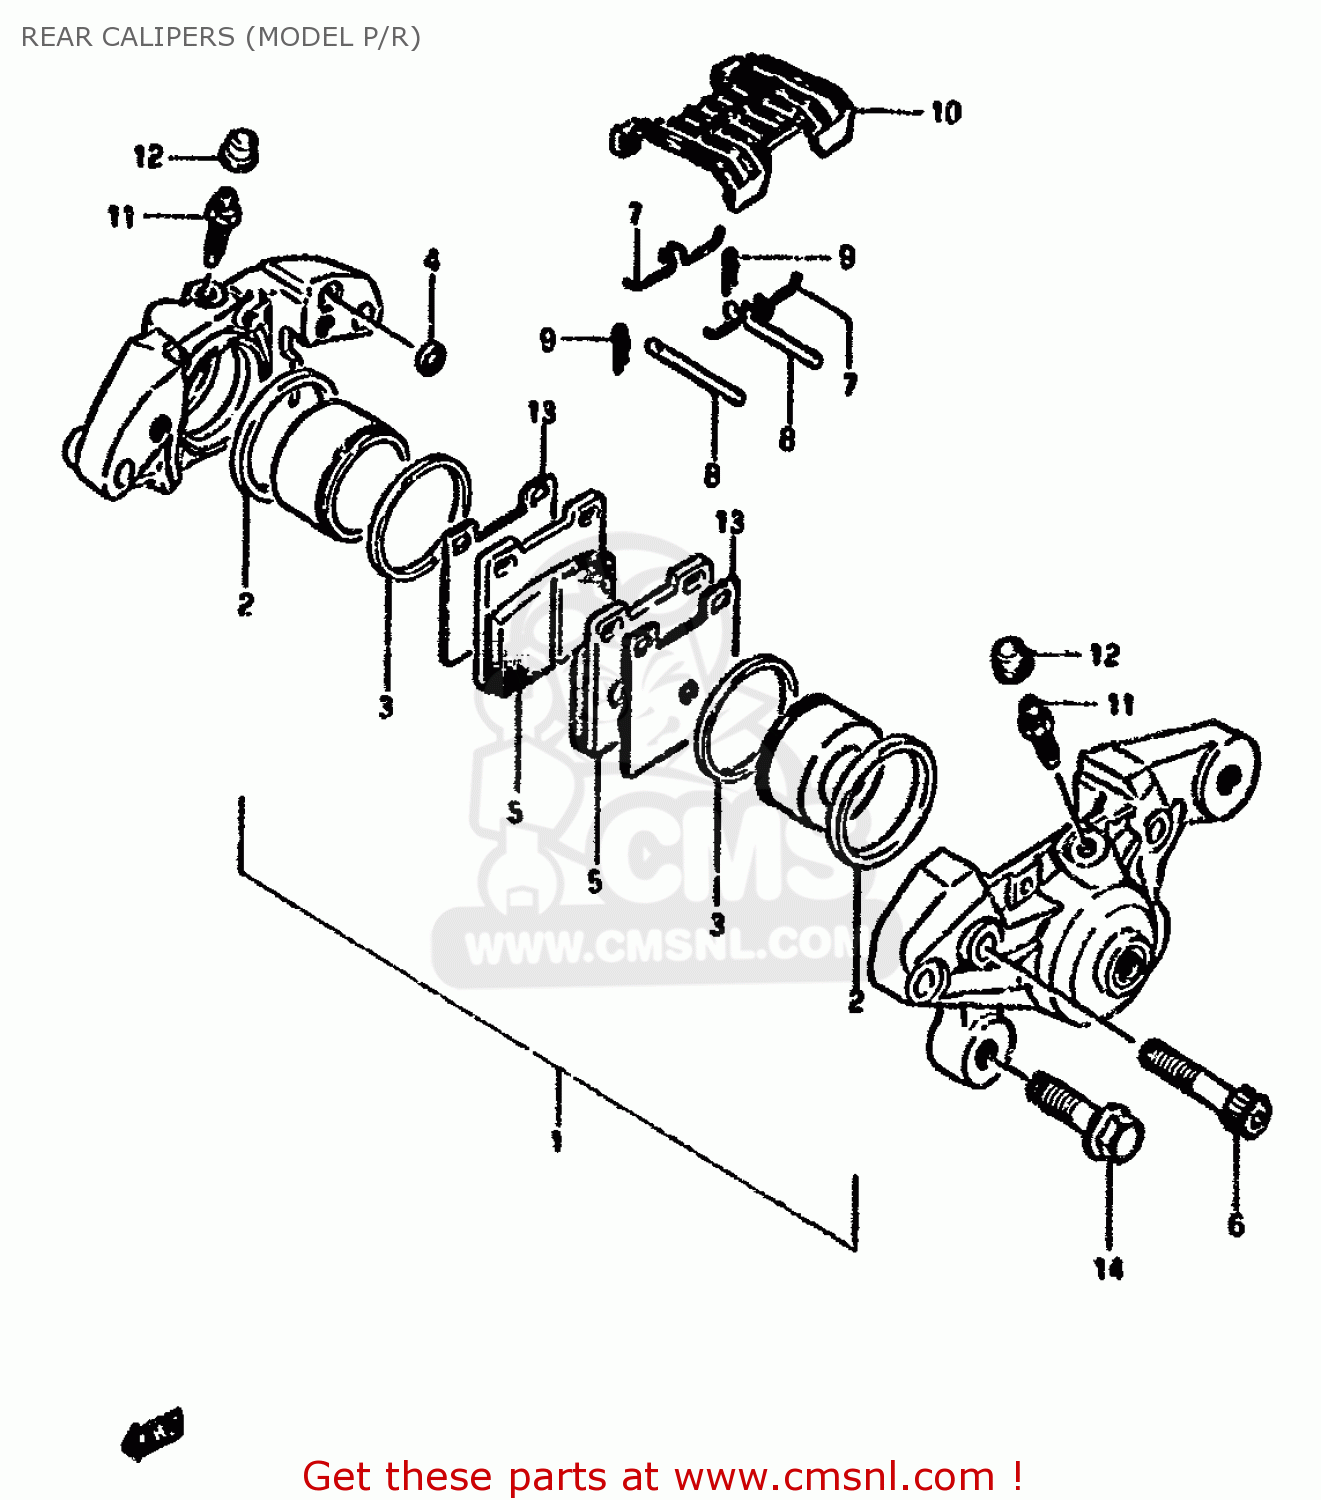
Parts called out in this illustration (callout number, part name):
1	PISTON SET
2	SEAL,PISTON
3	SEAL,WIPER
4	SEAL,JOINT
5	PAD,BRAKE
6	BOLT,CALIPER
7	SPRING
8	PIN,PAD
9	CLIP,PAD PIN
10	COVER,CALIPER
11	BLEEDER
12	CAP,BREATHER
13	SHIM,PAD
14	BOLT
